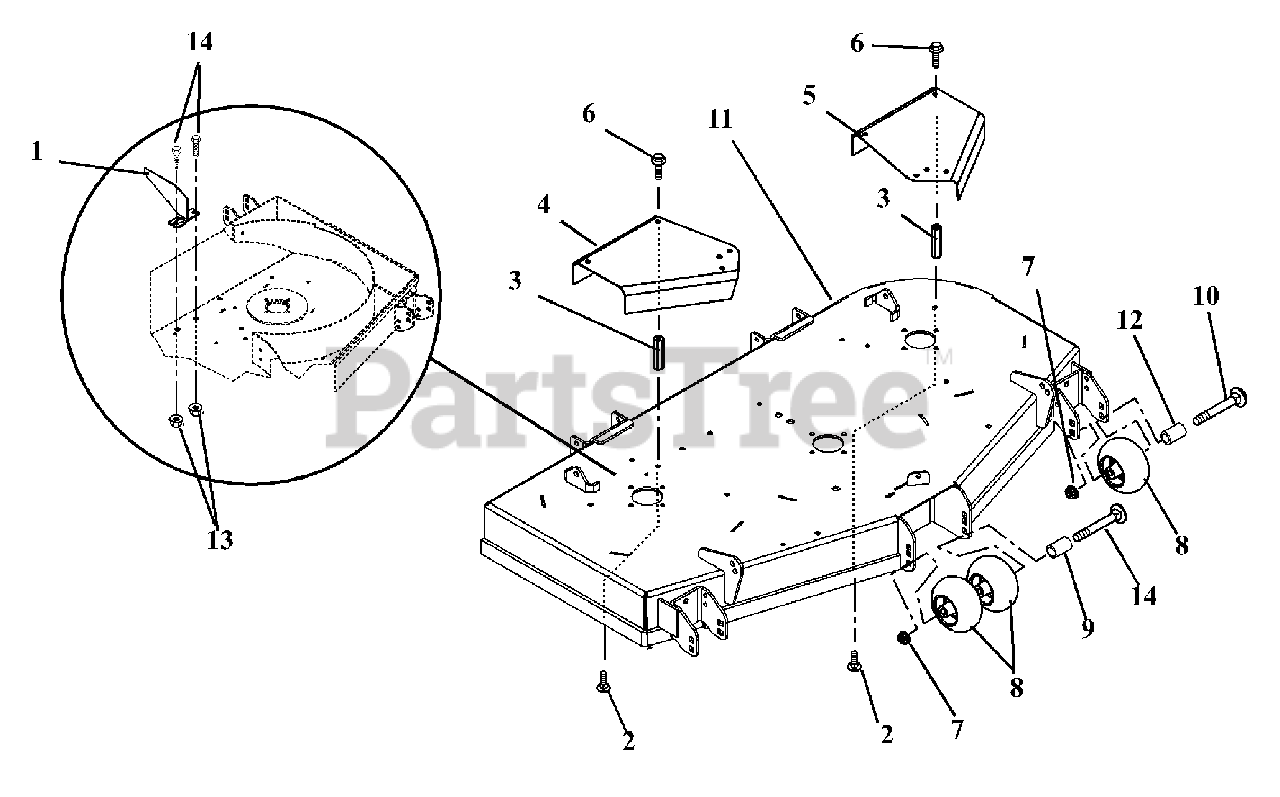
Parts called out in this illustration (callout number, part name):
1	REAR DISCH DEFLECT BFL WMT-RED
2	BLT,RDHDSQNK .31-18X.75 LOCTIT
3	NUT, COUPLING .31-18 X 3.00
4	48"-52" RH SPNDL SHV GUARD-RED
4	60"RH SPINDLE SHEAVE GUARD-RED
4	72"RH SPINDLE SHEAVE GUARD-RED
5	44"-52" LH SPNDL SHV GUARD-RED
5	60"LH SPINDLE SHEAVE GUARD-RED
5	72"LH SPINDLE SHEAVE GUARD-RED
6	BOLT, SEMS .31-18 X .62
7	@NUT-LK-NYL-FLG .50-13 YWZC
8	WHEEL, ANTI SCALP
9	SPACER, .510X.625X6.50
10	BLT-RDHDSQNK .50-13X5.00 GR5YZ
11	XDZ52" REAR DISCH DECK WMT-RED
11	XDZ60" REAR DISCH DECK WMT-RED
11	72"XDZ REAR DISCH DECK WMT-RED
12	SPACER, .510X.625X3.35
13	@NUT-LK-NYL-FLG .38-16 YWZC
14	@BLT-RDHDSHSQNK.38-16X1.0 G5YZ
